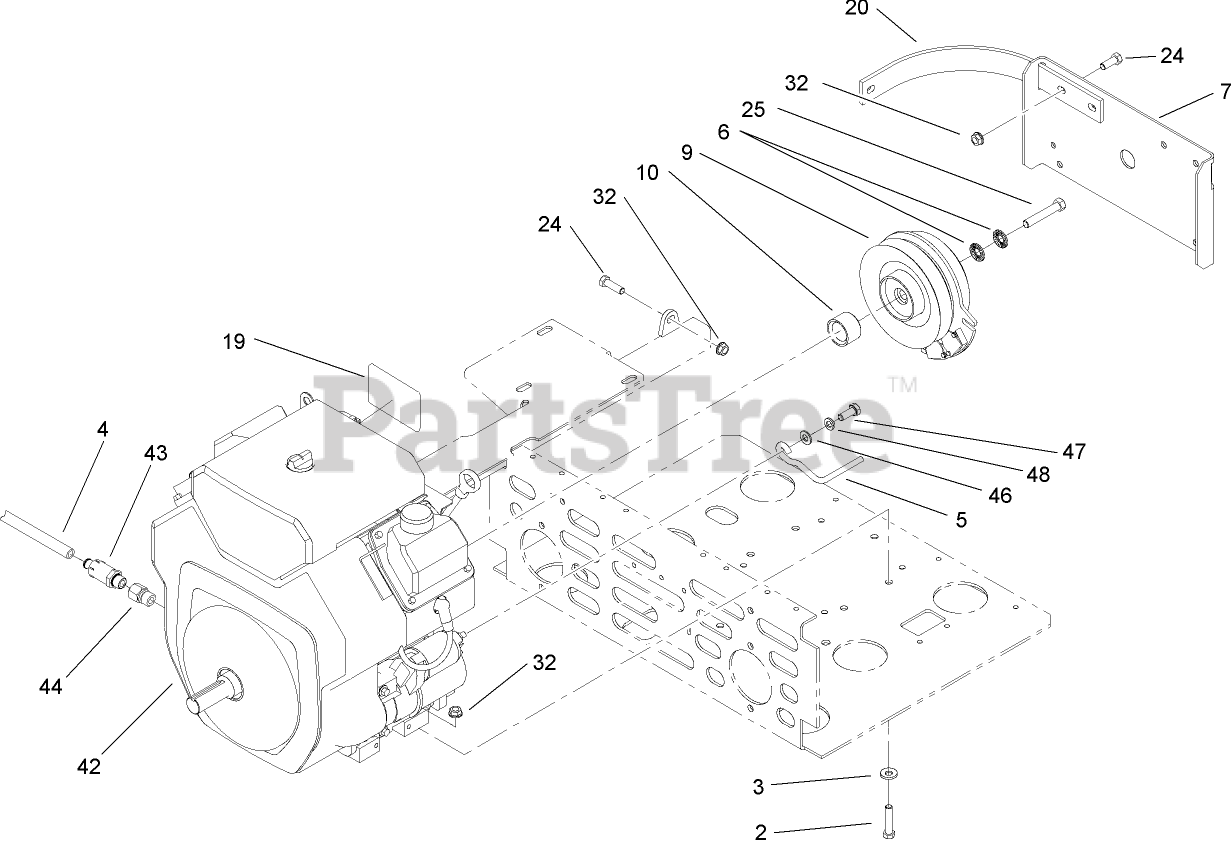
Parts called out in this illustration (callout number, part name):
2	SCREW-HH
3	WASHER-BELLEVILLE
4	TUBE-DRAIN, OIL
5	ROD-BELT
6	WASHER-SPRING
7	GUARD-CLUTCH
9	CLUTCH-ELECTROMAGNETIC
10	SPACER-CLUTCH
20	STRAP-GUARD
24	SCREW-HH
25	SCREW-HH
32	NUT-HHF, WHIZ
43	VALVE-DRAIN, OIL
44	Adapter
46	WASHER-FLAT
47	SCREW-HH
48	WASHER-BELLEVILLE
